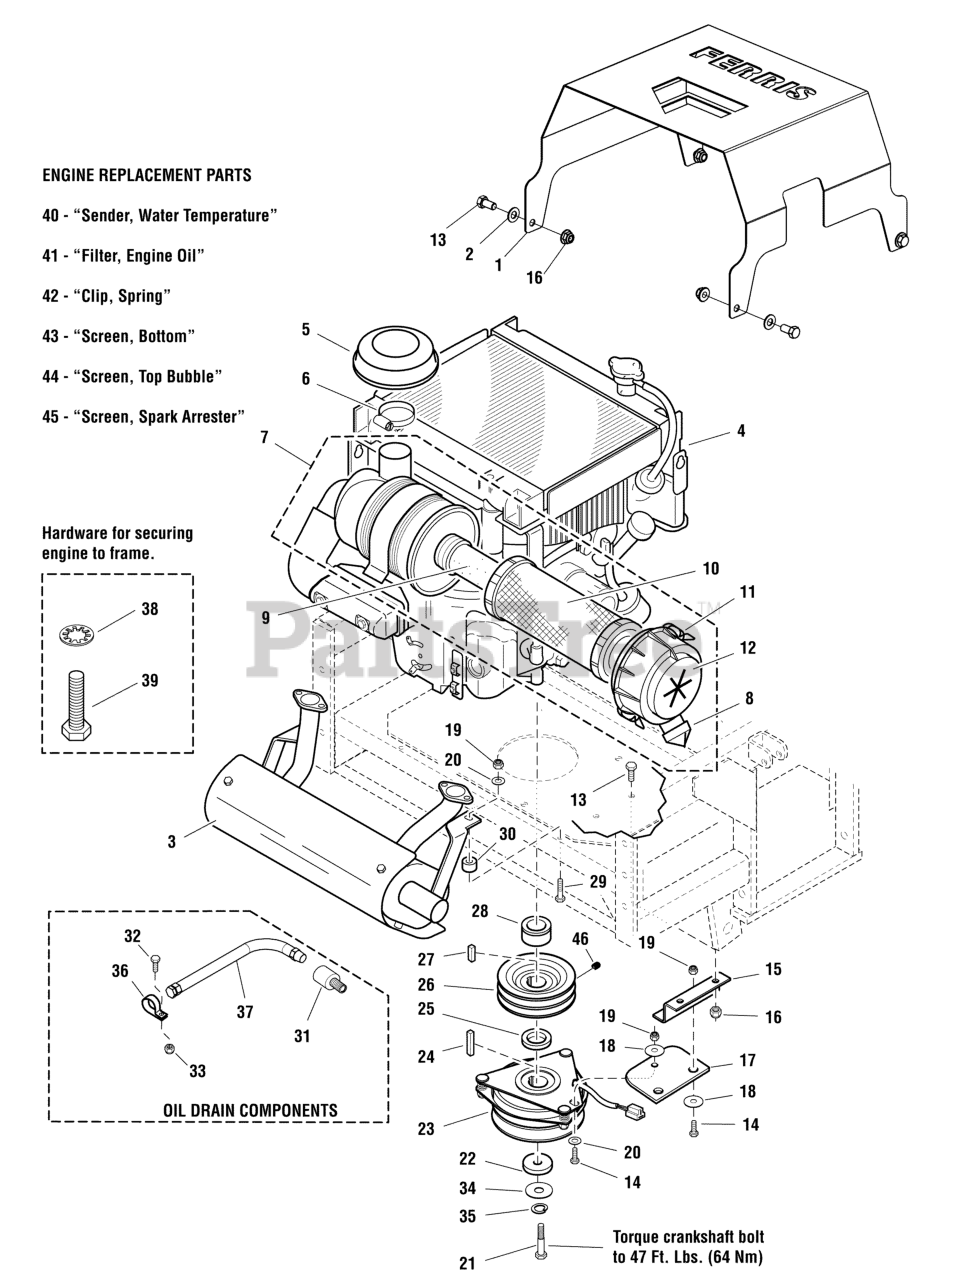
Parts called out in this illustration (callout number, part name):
1	GUARD, RADIATOR SCREEN PROTECTOR - RED
2	WASHER, 3/8 SAE
3	MUFFLER, KAWASAKI LC
4	ENGINE, KAWASAKI, LC
5	RAIN CAP
7	AIR FILTER ASSEMBLY, COMPLETE
8	RUBBER, Dust Valve
9	AIR FILTER, SECONDARY
10	AIR FILTER, PRIMARY
11	CLAMP, CAP
12	CAP, FILTER CASE
13	BOLT, 3/8-16 X 1" GD5 CZ
14	BOLT, 5/16-18 X 3/4
15	ANCHOR, CLUTCH - BLK
16	NUT, 3/8-16 HEX NYLOCK FLANGE
17	CLUTCH ANCHOR PAD
18	WASHER, 3/8" FENDER
19	NUT, 5/16-18 HEX NYLOCK FLANGE
20	WASHER, 5/16" SAE
21	BOLT, CRANKSHAFT, M10 X 65MM
22	SPACER, .406 X 1.88 X .38
23	CLUTCH, OGURA, 250 ft lbs - 1.13"
24	KEY, 1/4 SQ X 2
25	SPACER, 1.13 X 2.00 X .19
26	PULLEY, CRANKSHAFT (DOUBLE A)
27	KEY, 1/4 SQ X 1
28	SPACER, 1.13 X 1.75 X 1.03
29	BOLT, 5/16-18 X 1-3/4" GD5
30	SPACER, .39 X 1.00 X .80
31	ADAPTER, OIL DRAIN
32	BOLT, 1/4-20 X 1" GD5 CZ
33	NUT, 1/4-20 HEX NYLOCK FLANGE
34	WASHER, 7/16" SAE
35	WASHER, LOCK, 10MM
36	CLAMP, VINYL
37	HOSE, OIL DRAIN
38	WASHER, 5/16" INT. TOOTH LOCK
39	BOLT, M8-1.25 X 25MM GD8.8
40	SENDER, WATER TEMPERATURE
41	OIL FILTER, KAWI # 49065-2086
45	SCREEN, SPARK ARRESTER
46	SET SCREW, 5/16-18 X 3/8, KNURL, W/PATCH
